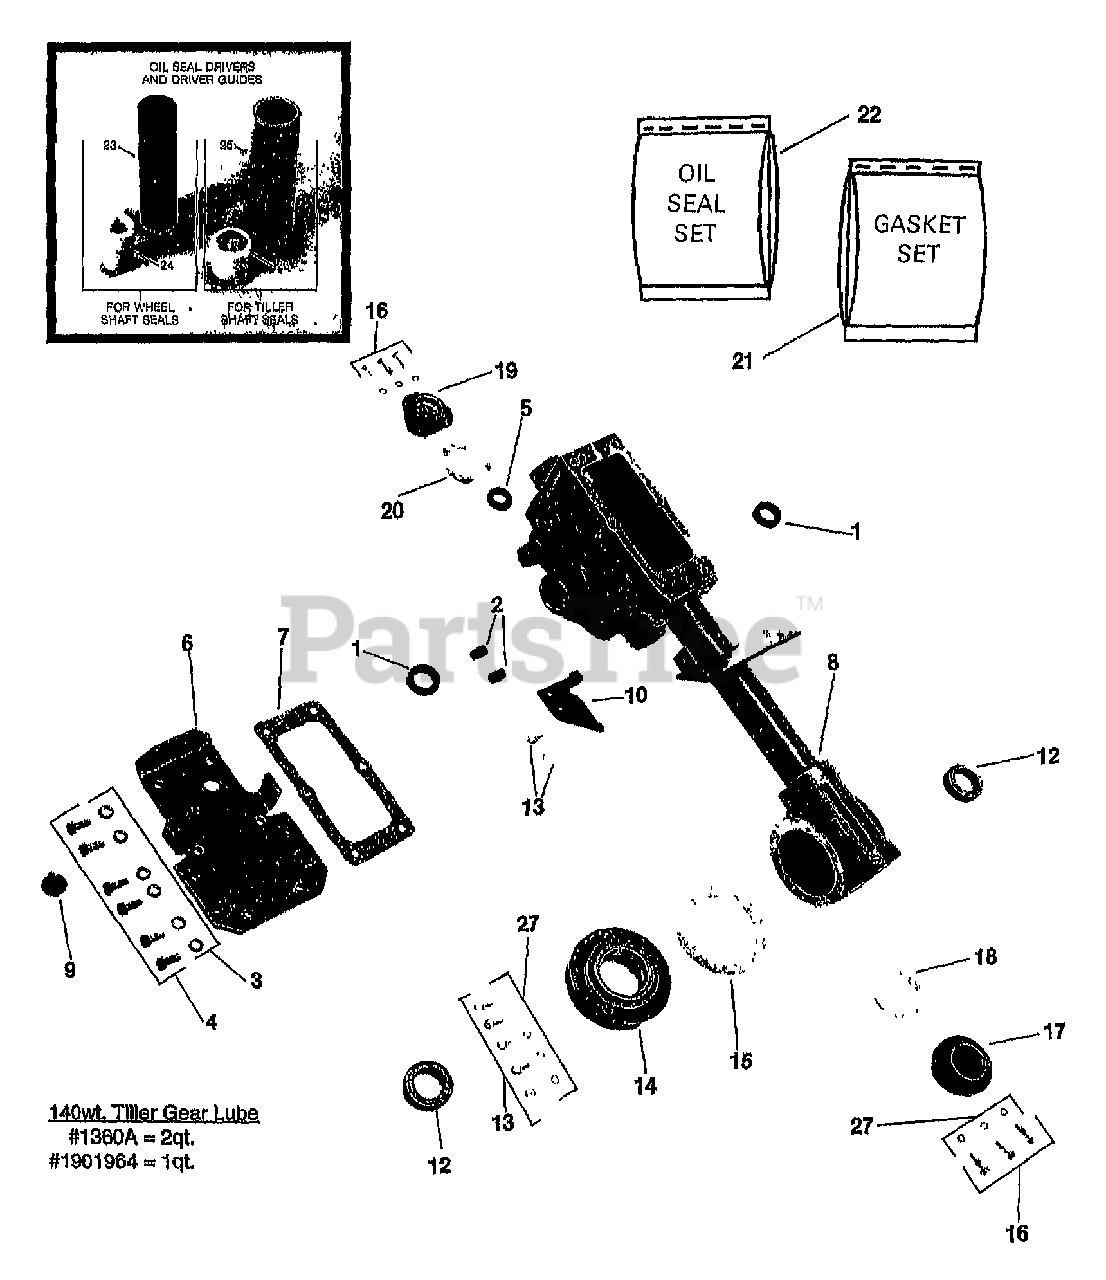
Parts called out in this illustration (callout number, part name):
1	SEAL-OIL WHEELSHAFT
2	PLUG-PIPE 1/4 NPT
3	WASHER-LK .312 ZP
4	SCR-HHC 5/16-18X.75 GR 5 ZP
5	SEAL-PINION SHAFT PT/85030/00
6	COVER-TRANS
7	GASKET-TRANS COVER
8	HSG-TRANS ONLY P4 (INCL. #9402)
9	PLUG-OIL FILL 3/4-10
10	PLATE-CABLE MOUNT PNT
12	SEAL-OIL TILLERSHAFT
13	SCR-HH 1/4-20X.625
14	COVER-W/SCRS(TLR) (9780)
15	GASKET-TILLER COVER (FITS ALL COVERS)
16	SCR-HFLK 1/4-20X.875
17	CAP-REAR #1115
18	GASKET-BRG COVER
19	COVER-FRONT BEARING
20	GASKET-FRONT COVER-.010
21	GASKET SET-P4
22	KIT-OIL SEAL SET-P4
23	DRIVER-PLASTIC (USE WITH PART #4921-2)
24	SEAL-DRIVER PILOT (USE WITH PART #4921-1)
25	H&P SEAL DRIVER (USE WITH PART #1961-2)
27	WASHER - NYLON, NOT REUSABLE (SEE KIT)
